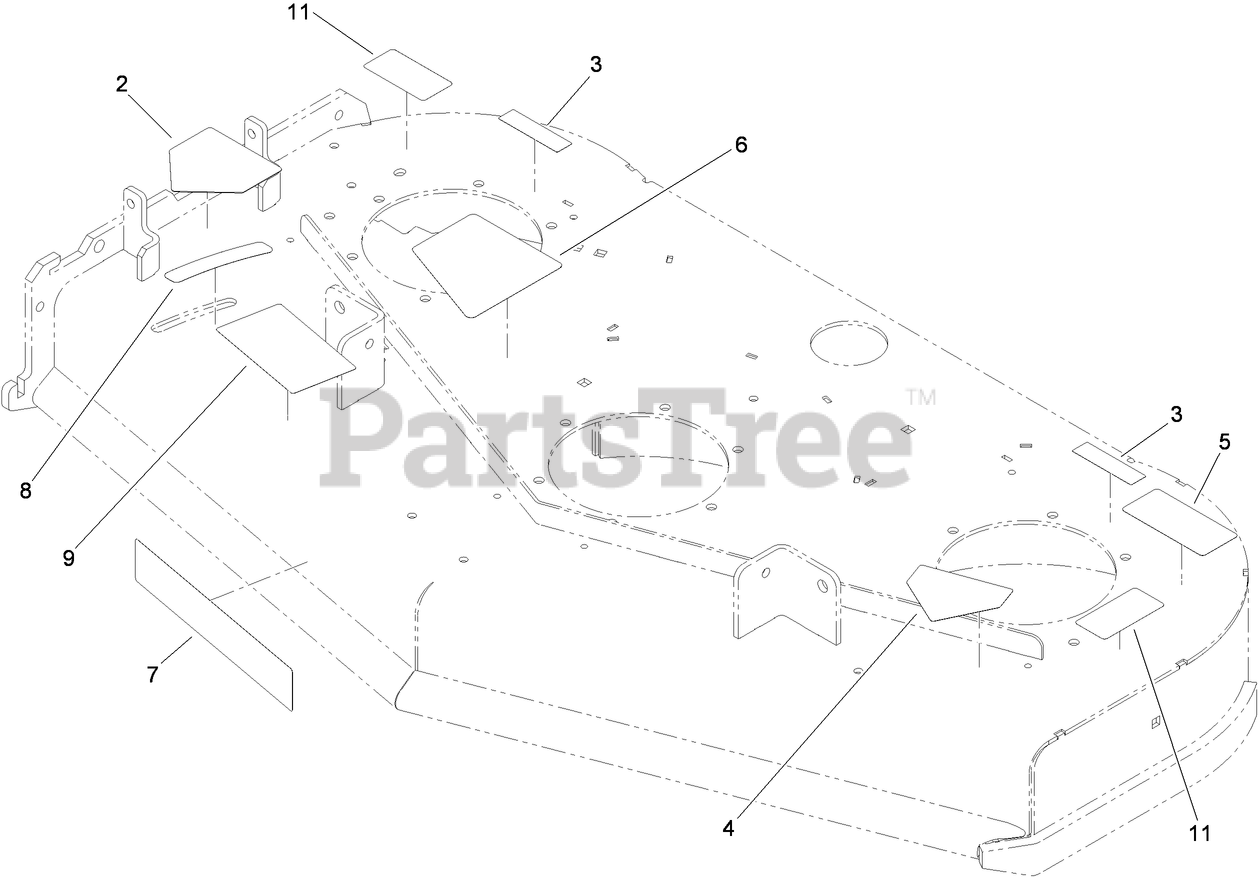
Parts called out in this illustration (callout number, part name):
2	DECAL-DANGER
3	DECAL-COVER, MISSING
4	DECAL-DANGER
5	DECAL-TORQUE
6	DECAL-TENSION, BELT
8	DECAL-SETTING, BAFFLE
9	DECAL-ADJUSTMENT, BAFFLE
11	DECAL-ROTATING PARTS
